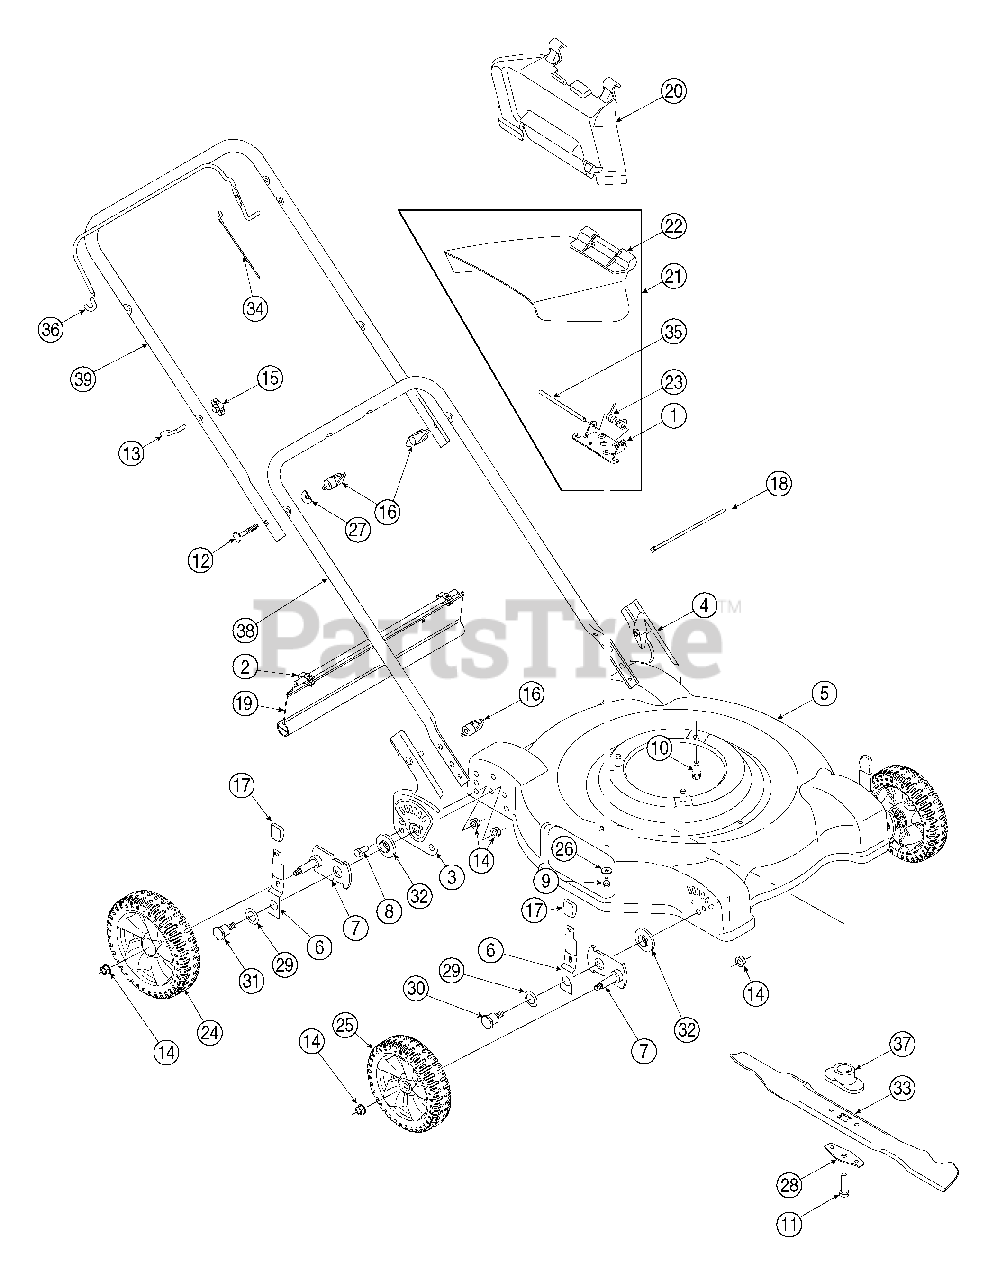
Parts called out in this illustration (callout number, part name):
1	Chute Hinge
2	Hinge Clip
6	Lever Assembly
7	Pivot Arm
8	Hex Cap Screw 3/8-16 x .75
9	TT Screw 1/4-20 x 0.5"
10	TT Screw 3/8-16 x 1.0
11	Hex Cap Screw 3/8-24 x 1.5
12	Carriage Bolt 5/16-18 x 2.0
13	Eye Bolt
14	Lock Nut 3/8-16
15	Wing Nut
16	Wing Nut
17	Height Adjuster Knob
18	Cable Tie
19	Trail Shield
20	Mulching Plug
21	Hinged Chute Deflector Assembly
22	Chute Deflector
23	Torsion Spring
24	Rear Wheel 8 x 1.8
25	Front Wheel 7 x 1.8
26	Bell Washer .265 ID x .75 OD
27	Saddle Washer .320 ID x .93 OD
28	Blade Bell Support
29	Bell Washer .760 ID x 1.25 OD
30	Shoulder Screw
31	Shoulder Screw
32	Height Adjuster Bearing
33	Standard Blade 22"
34	Blade Control Cable - 37.25"
35	Hinge Pin
37	Blade Adapter
